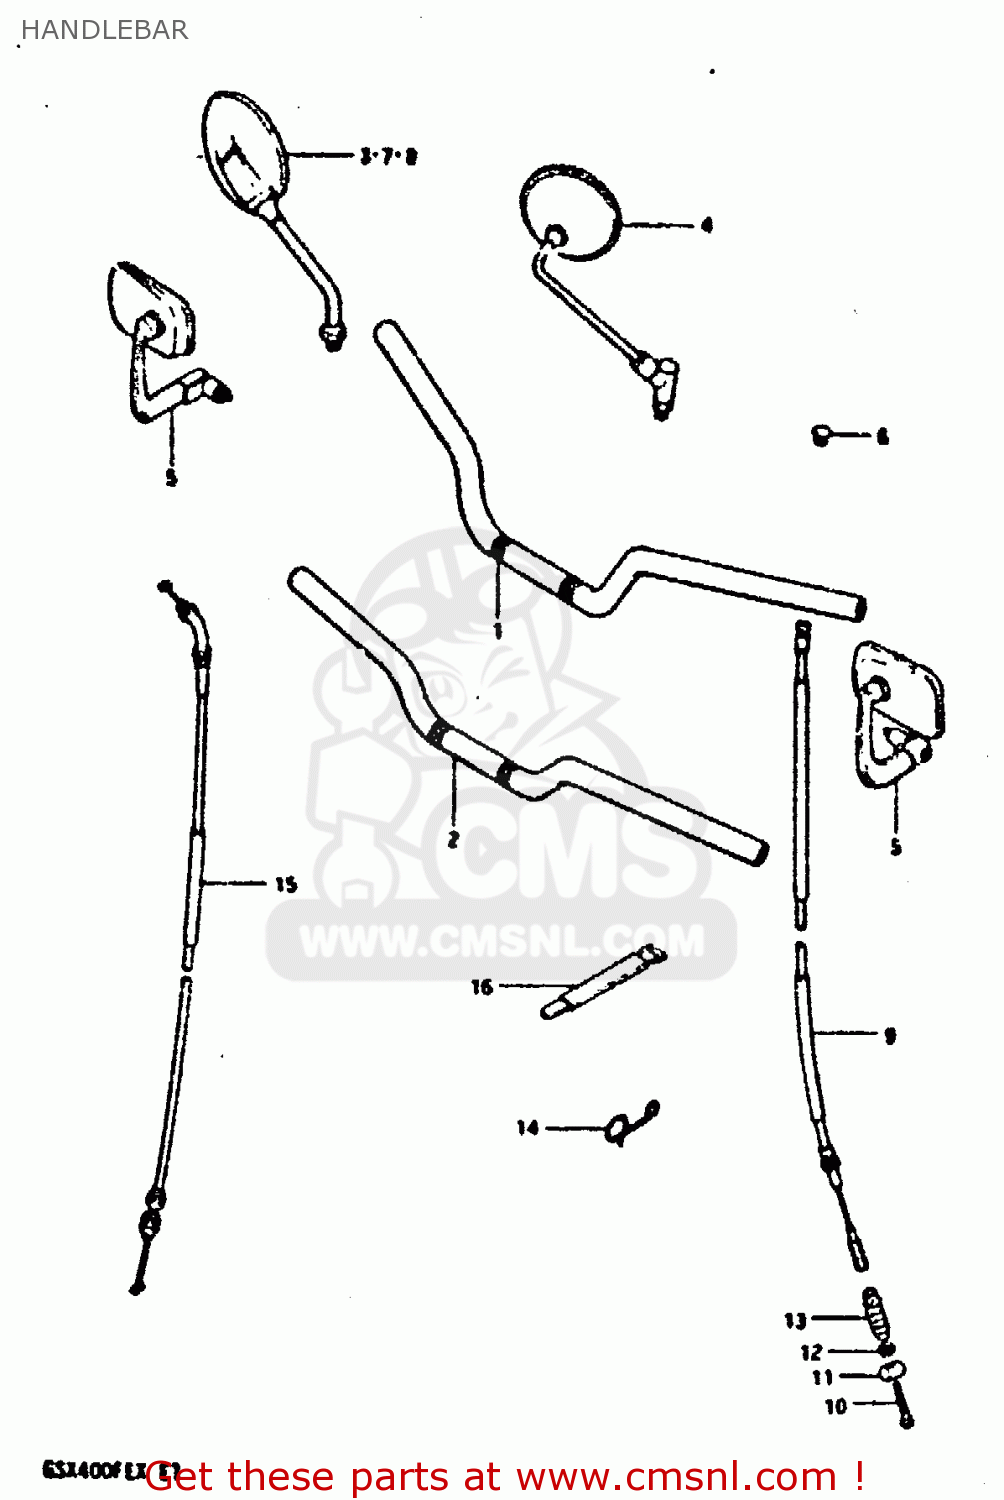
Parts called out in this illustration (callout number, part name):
1	HANDLEBAR (NERTRAL)
2	HANDLEBAR (FLAT)
4	MIRROR, REAR VIEW
6	CAP(OD:14)
9	CABLE, CLUTCH (FLAT)
10	SCREW
11	PIN
12	NUT
13	DUST SEAL
14	GUIDE,CLUTCH CABLE
15	CABLE ASSY,THR
16	CLAMP
